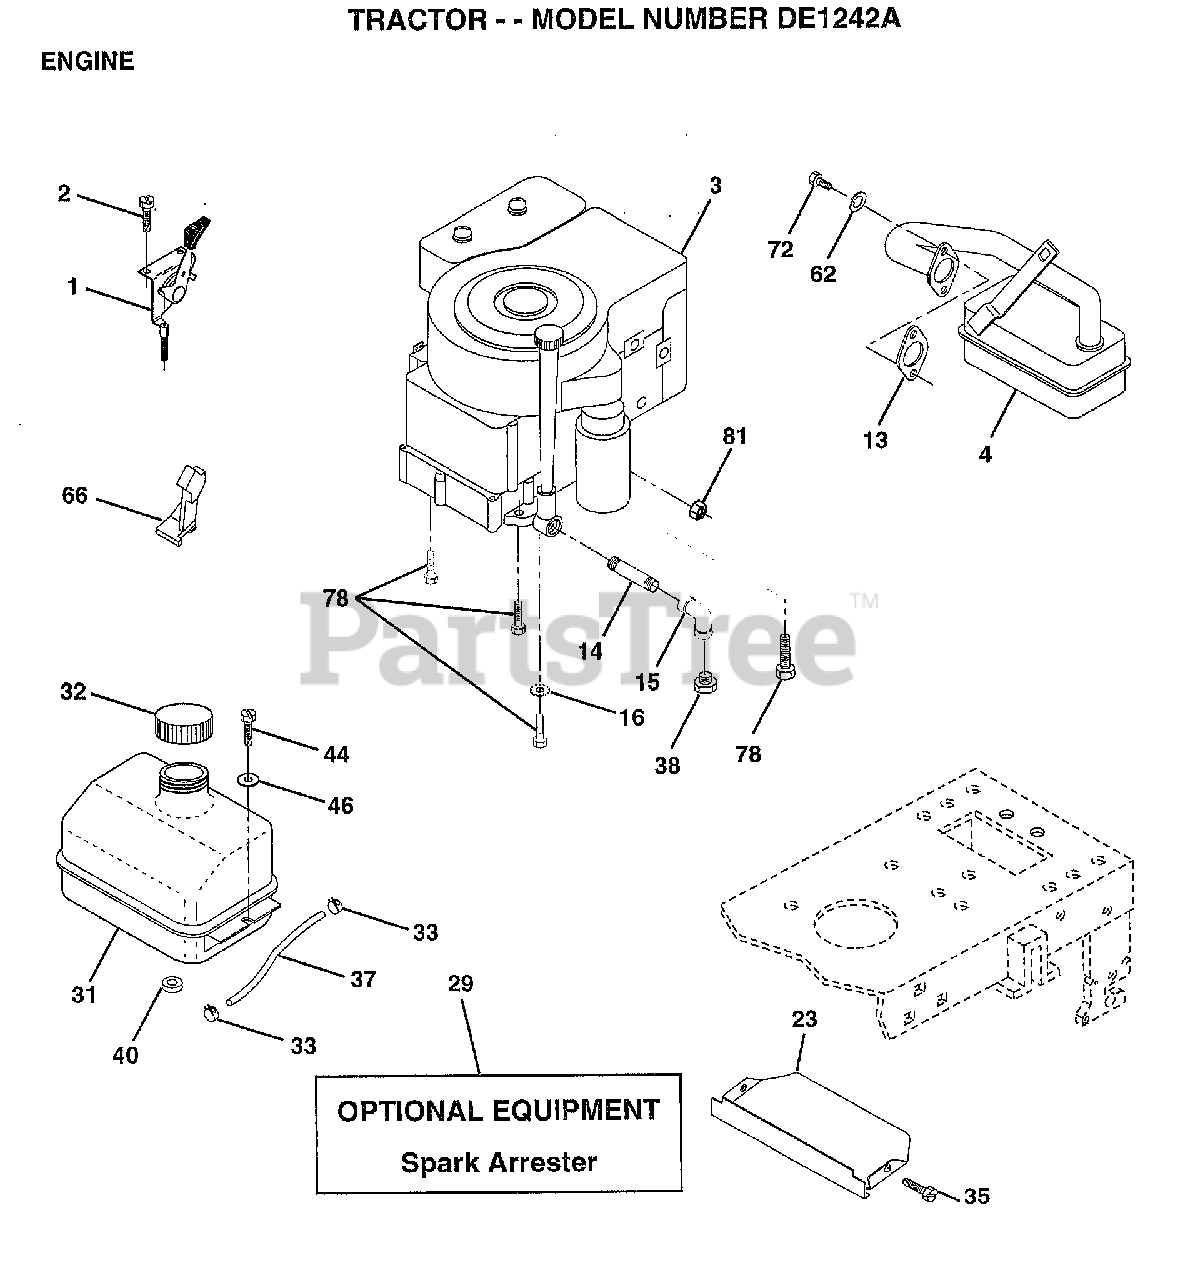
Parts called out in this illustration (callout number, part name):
1	CONTROL.THTL.23.5
2	SCREW LT
4	MUFFLER
13	GASKET ENG 1 313 LD TIN PLATED
14	PIPE NIPPLE
15	ELBOW
16	LOCKWASHER
23	SHIELD.BRN/DBR.GD
31	TANK.FUEL.LT.
32	CAP ASM FUEL
33	HOSE CLAMP
35	SCREW
37	LINE FUEL
44	SCREW HEX CRT
46	WASHER
62	LOCKWASHER
66	"STOP,DASH THROTT"
72	SCREW
78	SCREW
81	NUT
